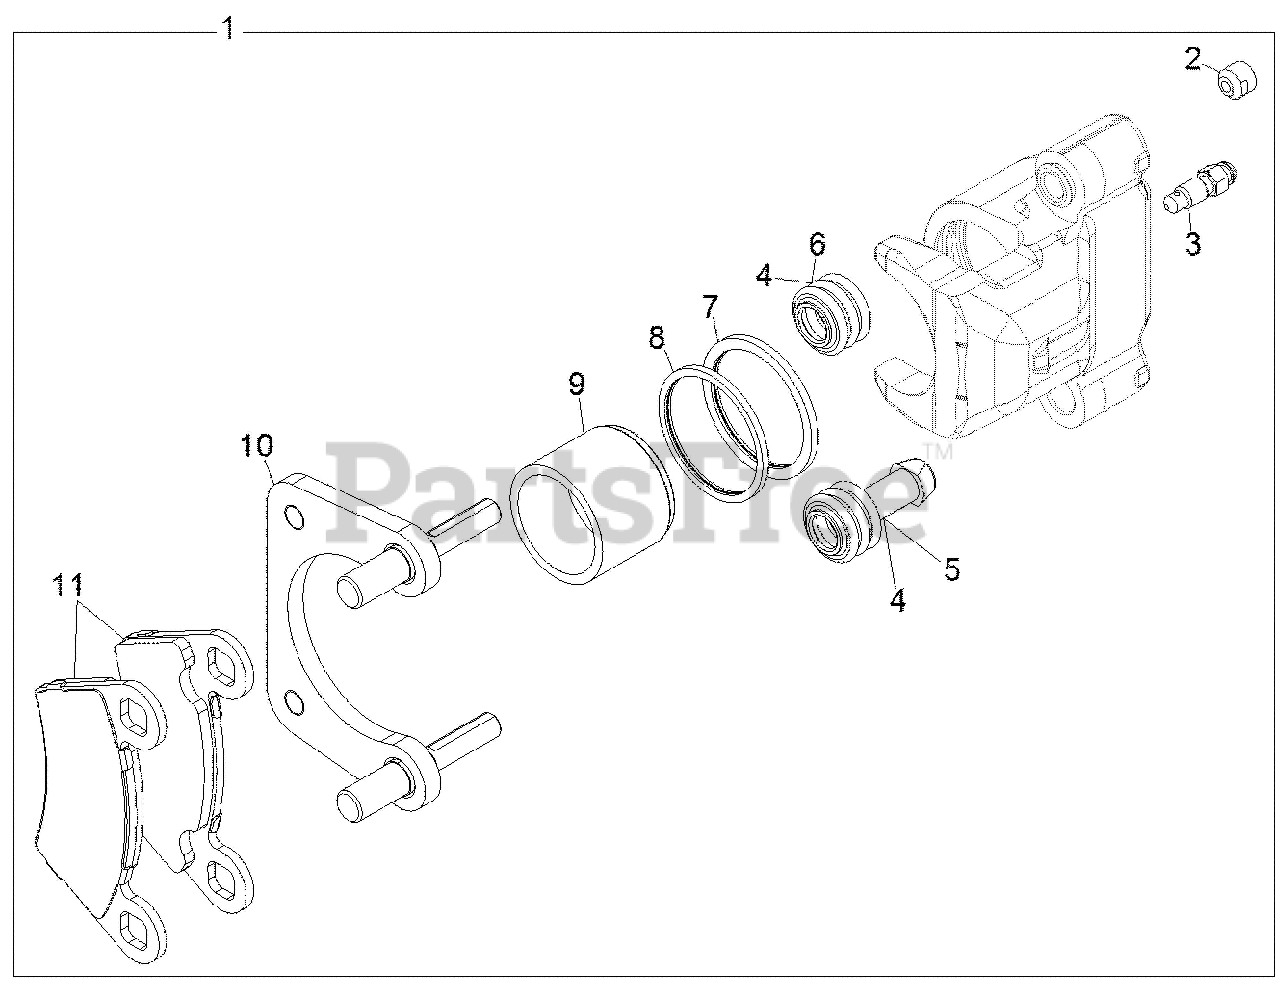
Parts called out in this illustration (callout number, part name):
1	ASM-CALIPER,BRAKE,1.5,LH,R MET
1	ASM-CALIPER,BRAKE,1.5,RH,R MET
2	SCR-M10X1.0X8,SOC SET-OD
3	SCR-M7X1.0,BLEEDER,OLIVE D
4	KIT,CROSS & BEARING,NONGREASE
5	BOOT-PIN BUSHING
6	BOOT-PIN SEAL
7	SEAL-CALIPER INNER,1.50"
8	SEAL-CALIPER,OUTER,1.50"
9	PISTON-BRAKE,1.500
10	ASM-CALIPER MOUNT,REAR,METRIC
11	KIT,BRAKE PAD
